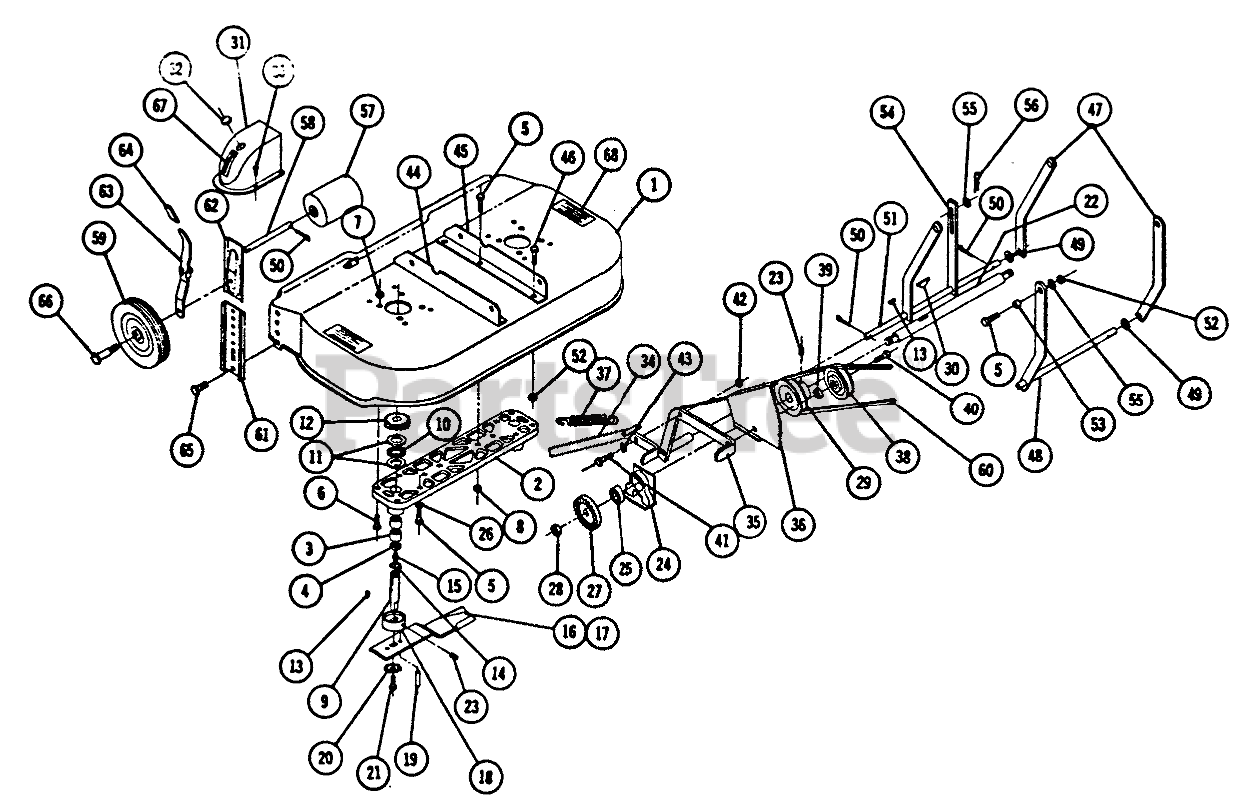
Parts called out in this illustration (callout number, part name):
1	Ass-y. Deck
5	Bolt 3/8-16 x 1
6	Bolt 5/16-18 x 1
7	Nut-Nylok
9	SPINDLE SHAFT
19	SPIROL ROLL PIN
21	Bolt 3/8-16 x 7/8
23	Set Screw
26	Lockwasher
28	Nut Hex 5/8-18 Thin
32	PLUG BUTTON
33	SCREW
35	59027 1969 OPC
40	Bolt 3/8-16 x 7/8
41	Bolt-Hex 1/4-20
42	Nut-Nylok
43	Washer
44	Bracket Mtg. R.H.
45	Bracket Mtg. L.H.
46	Bolt 3/8-16 x 3/4
47	Link Mower Hanger
49	Washer
50	Cotter Pin 1/8 x 1
52	3/8-16 E.S.
55	Washer
56	Hairpin
62	HT ADJ SLIDE
63	HT ADJ SPRING LEVER
66	BOLT SHOULDER
67	Decal
